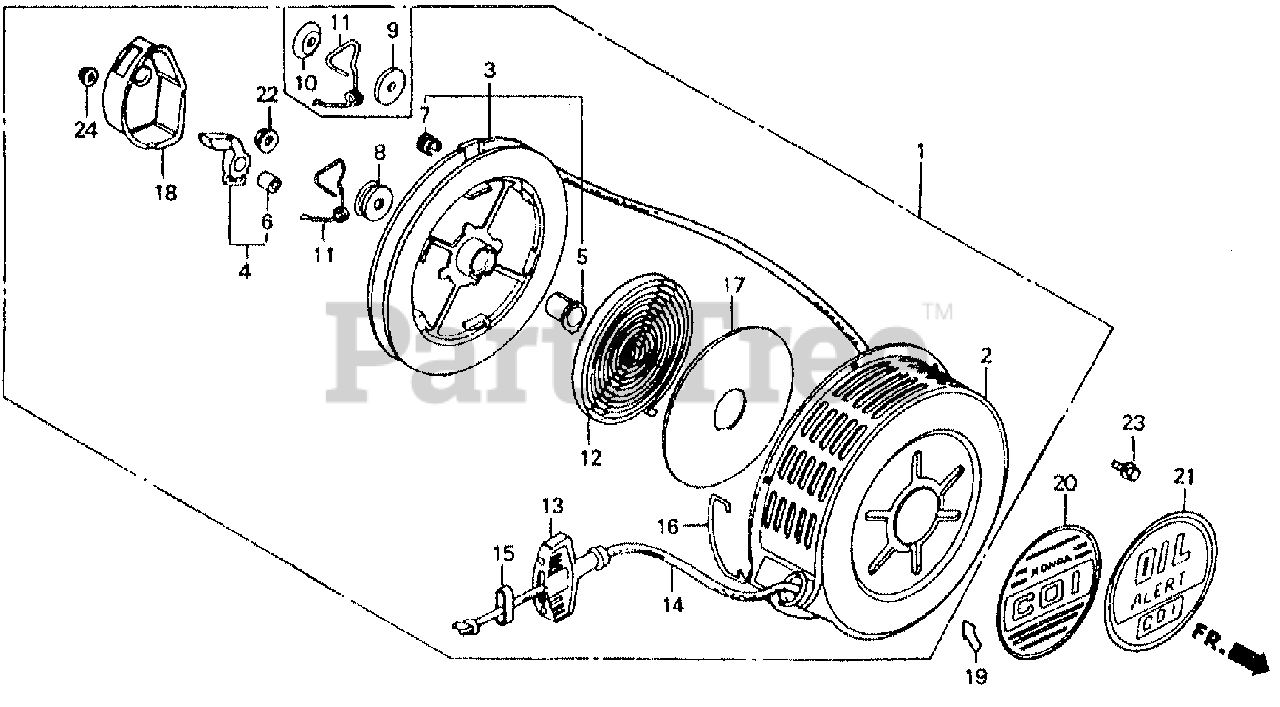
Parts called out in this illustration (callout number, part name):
1	STARTER ASSY., RECOIL *R8* (BRIGHT RED)
2	CASE, STARTER *R8* (BRIGHT RED)
3	REEL, STARTER
4	RATCHET
5	BOSS, REEL
6	BUSH, RATCHET
7	BUSH, REEL STARTER
9	PLATE, FRICTION
10	PLATE, FRICTION
11	SPRING, FRICTION
12	SPRING, RETURN
13	GRIP, STARTER
14	ROPE, STARTER (#6X64")
15	SUPPORT, GRIP
16	HOLDER, ROPE
17	PLATE, SIDE
18	COVER, REEL STARTER
19	MARK, STARTING
20	MARK, C.D.I.
22	NUT, SELF-LOCK (8MM)
23	BOLT-WASHER (6X10)
24	NUT, FLANGE (6MM)
